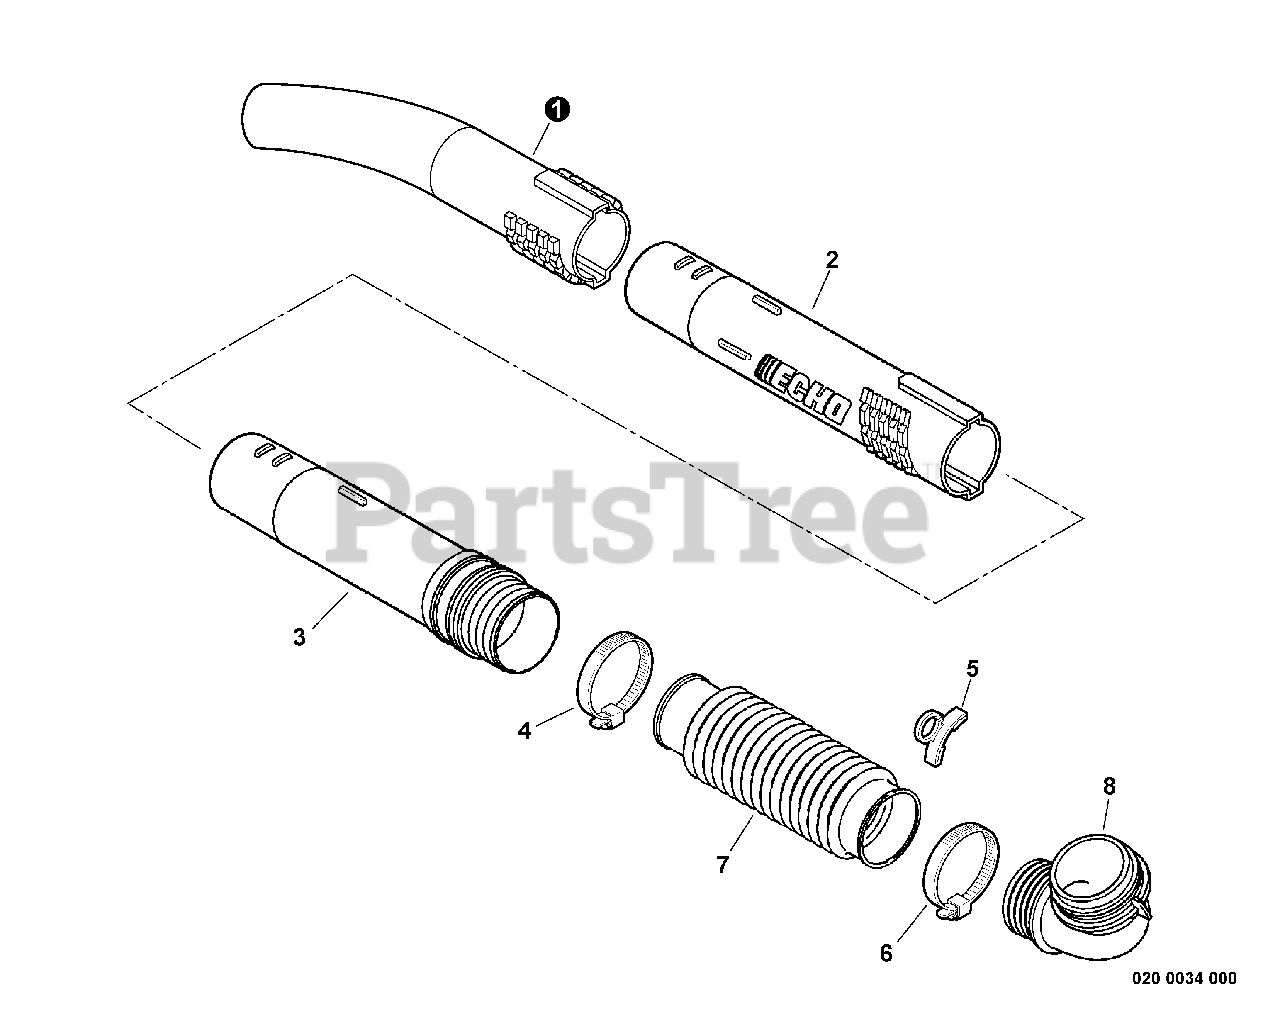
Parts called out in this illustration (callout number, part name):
1	TUBE, BLOWER - NOZZLE
2	TUBE, BLOWER - STRAIGHT
3	TUBE, BLOWER - SWIVEL
4	CLAMP, HOSE
5	CLIP, CABLE
6	CLAMP, HOSE
7	TUBE, BLOWER - FLEXIBLE
8	TUBE, BLOWER - ELBOW
